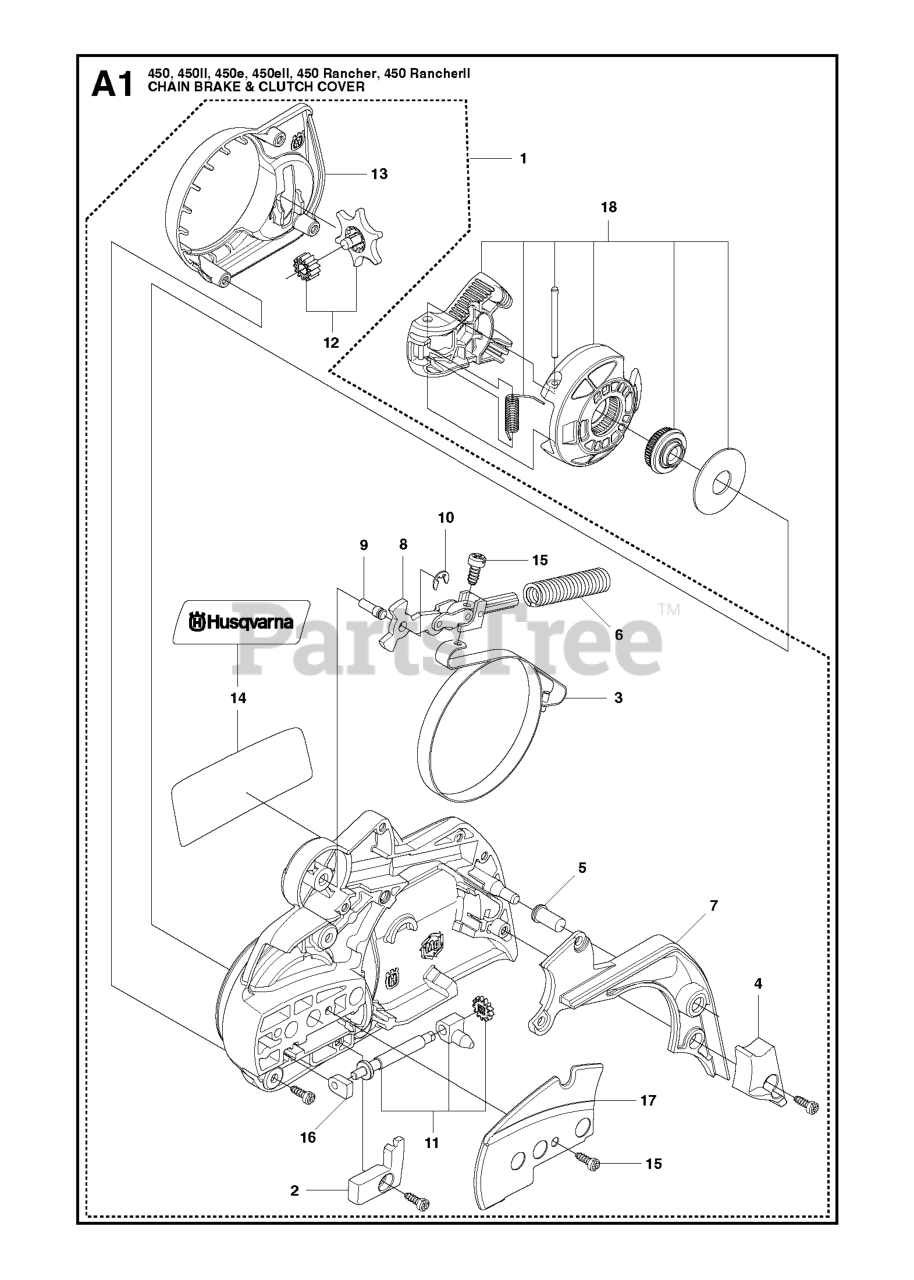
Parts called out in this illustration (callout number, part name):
1	Covers
3	BRAKE BAND
4	WEAR GUARD, CHAIN
7	COVER, CHAIN BRAKE
11	CHAIN TENSIONER SCREW, COMP.
12	CHAIN TENSIONER WHEEL, COMP.
13	HEAT SHIELD
14	DECAL, CLUTCH HOUSING
16	BEARING SLEEVE
18	KNOB, COMPLETE
